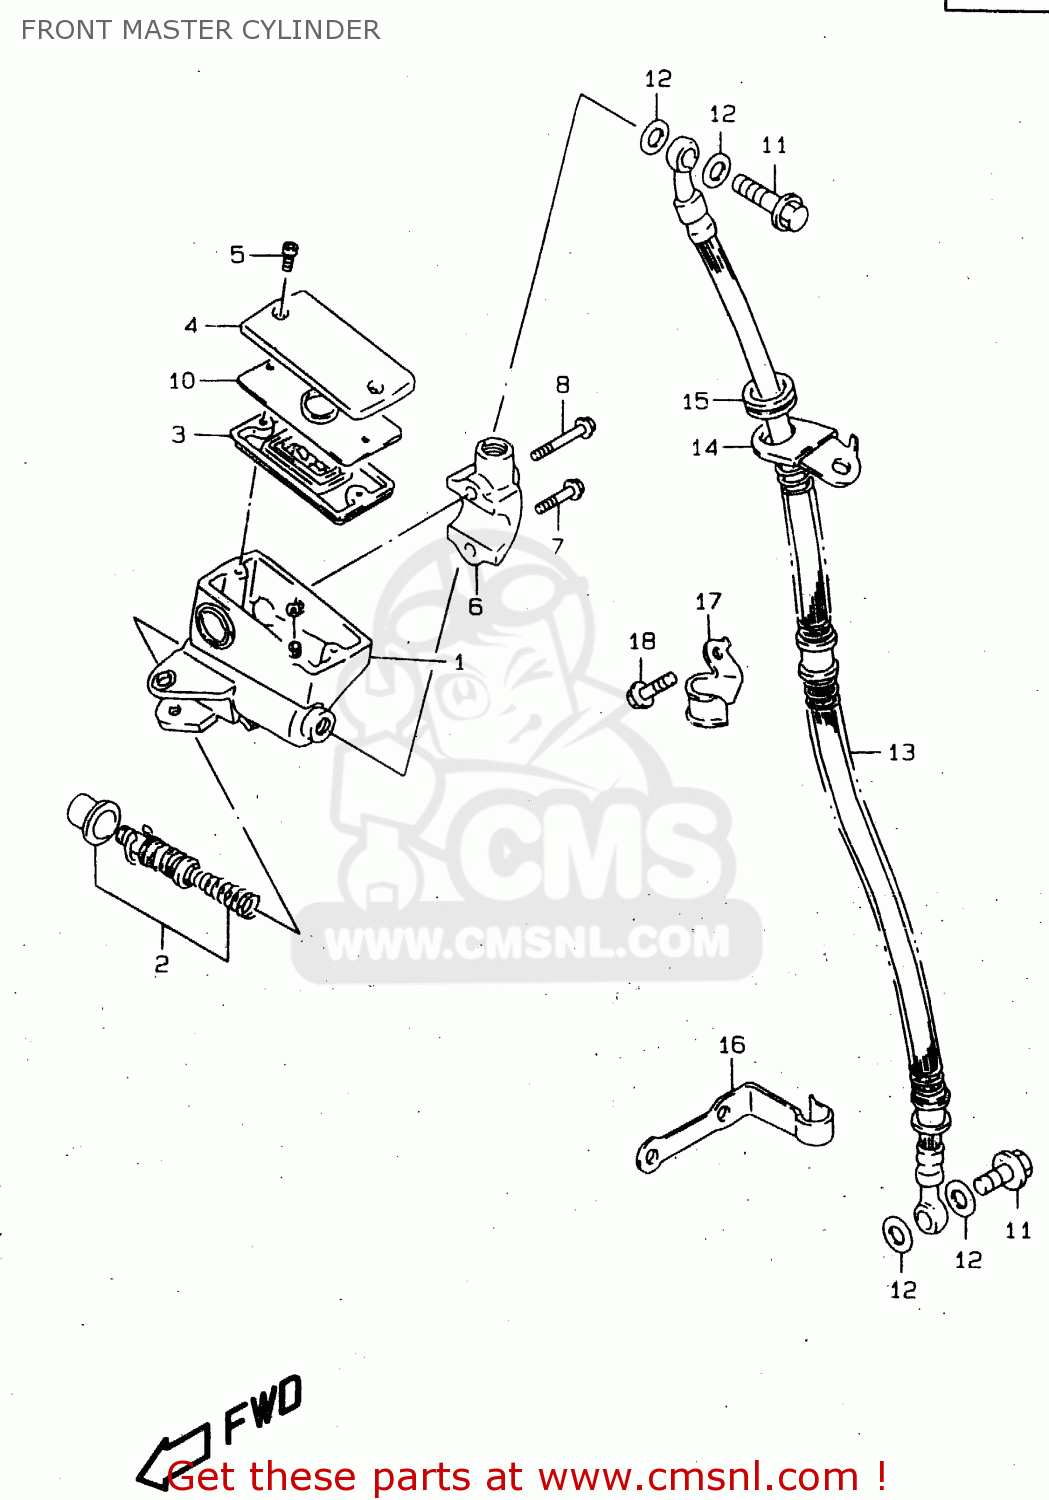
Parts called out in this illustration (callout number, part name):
1	CYLINDER ASSY,FR MASTER
2	PISTON & CUP SET
3	4
4	CAP
5	SCREW
6	HOLDER
7	BOLT(6X25)
8	BOLT(6X38)
9	PROTECTOR
10	PLATE,DIAPHRAGM
11	BOLT UNION
12	WASHER(10X15X1.5)
13	HOSE,FR BRAKE
14	GUIDE,BRAKE HOSE
15	GROMMET
16	CLAMP,BRAKE HOSE
17	GUIDE,BRAKE HOSE NO.3
18	BOLT
